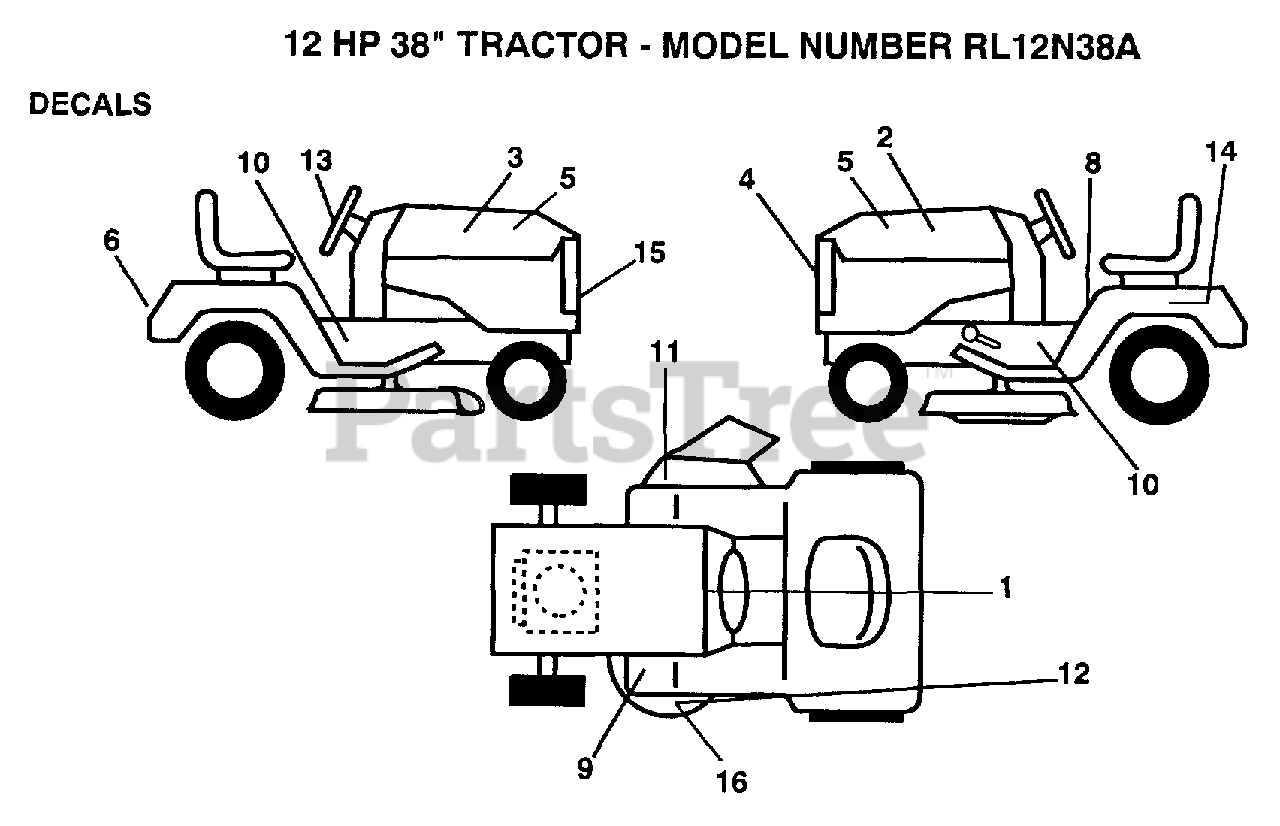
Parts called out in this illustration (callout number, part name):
4	GRILL DECAL
6	FENDER DECAL
8	DECAL CAUTION
9	DECAL T
10	DECAL CHASSIS SPEED DECK
11	DECAL WARNING
12	DECAL YT
13	"DECAL,STR WHL"
14	DECAL
